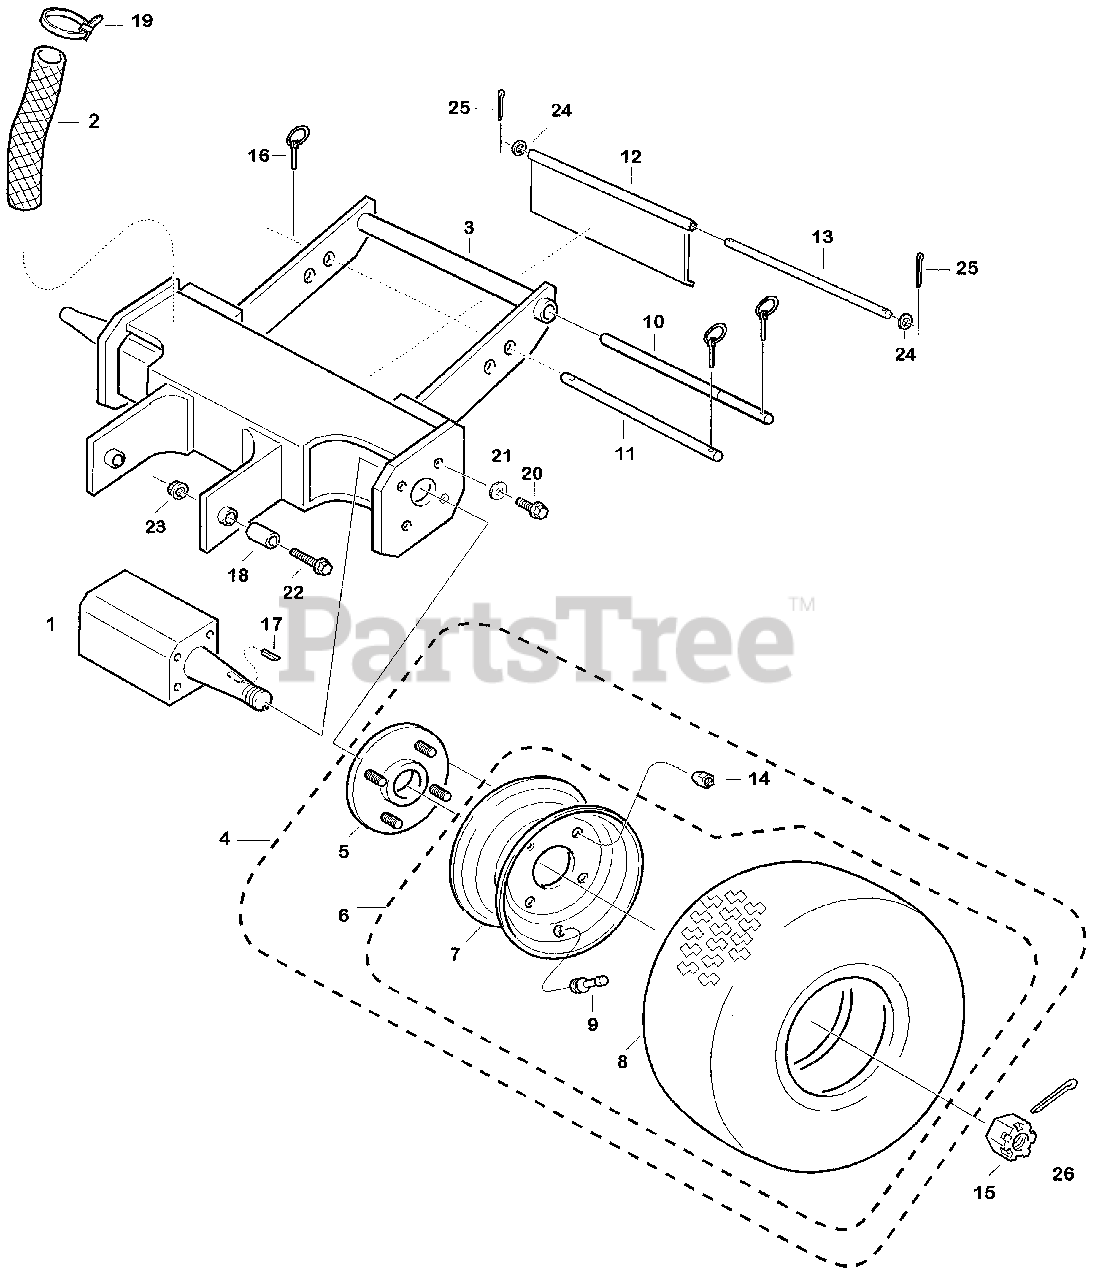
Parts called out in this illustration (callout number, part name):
1	MOTOR ASSY., HYDRAULIC
2	COVER, HOSE
4	WHEEL ASSY., TRACTION
5	HUB, WHEEL
6	WHEEL ASSY., RR.
7	WHEEL, RR.
8	TIRE, RR.
9	VALVE, RIM
10	BAR, HEIGHT
11	SHAFT, HEIGHT (NOT AVAILABLE)
12	SHIELD, RR. (NOT AVAILABLE)
13	ROD, RR. SHIELD
14	LUG NUT, HEX. (1/2"-20)
15	NUT, STRAIGHT SLOT (3/4"-16)
16	QUICK CLIP
17	KEY, WOODRUFF
18	BUSHING, AXLE
